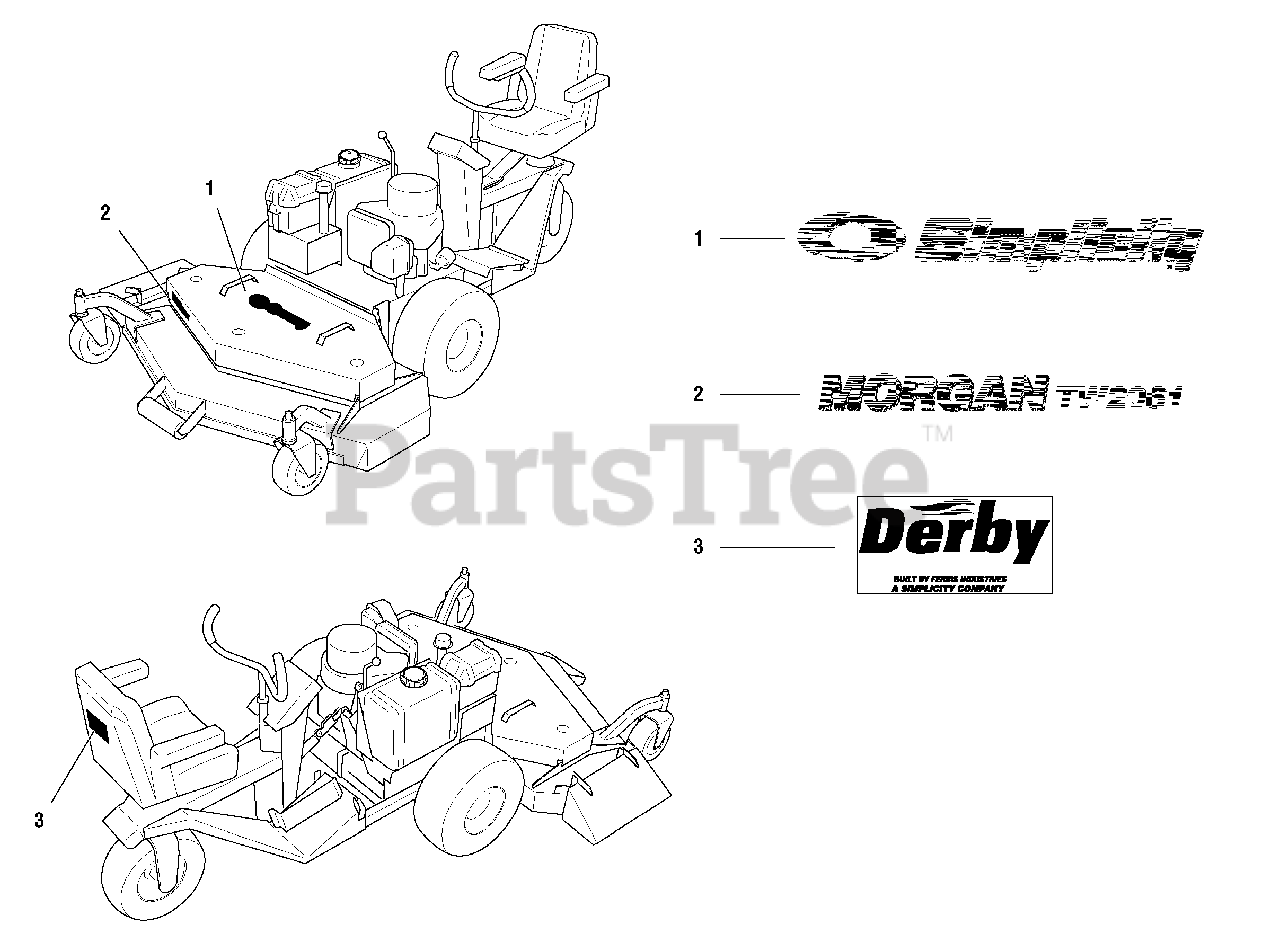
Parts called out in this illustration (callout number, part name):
1	DECAL, Simplicity Logo
2	DECAL, Morgan TW2061
3	DECAL, Derby Built By Ferris
